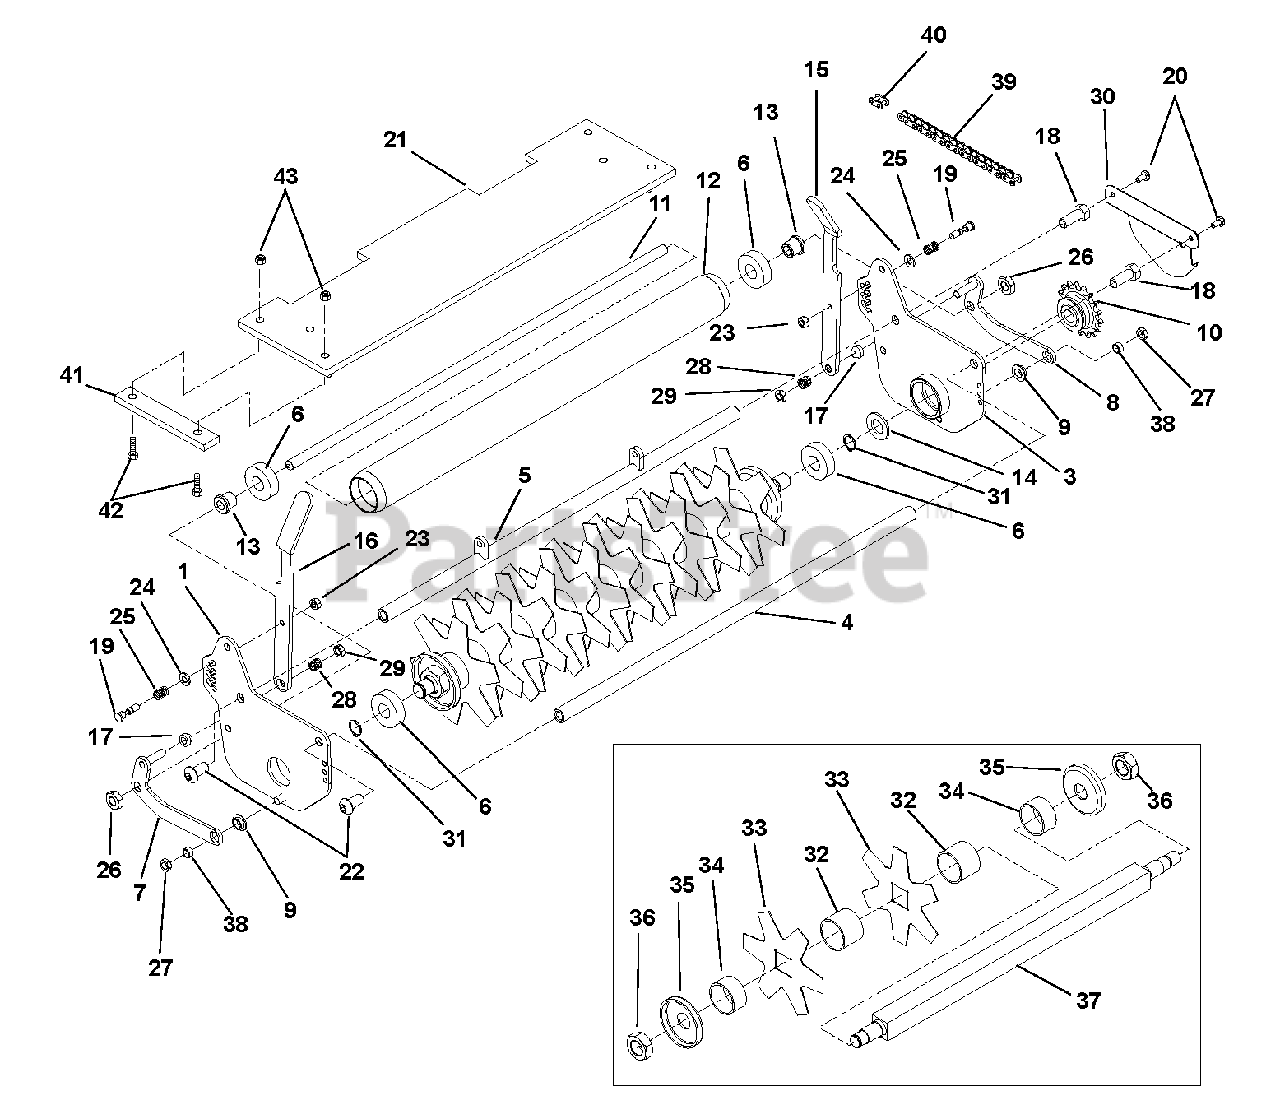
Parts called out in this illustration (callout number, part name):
1	Shaft Assembly, Verticutter (995030, 032)
2	End Plate, V-Cut Right Hand
3	End Plate, V-Cut Left Hand
4	Bar, Spacer 25-Inch (995030, 032)
5	Bar, Rear Spacer 25-Inch (995030, 032)
6	Bearing, 47 mm x 20 mm x 14 mm
7	Arm, Rear Roller Height Right Hand
8	Arm, Rear Roller Height Left Hand
9	Bushing, Sintered Steel, Oil Impregnated
10	Sprocket, 17 Tooth
11	Axle, Roller 25-Inch (995030, 032)
12	Tube, Roller 25-Inch (995030, 032)
13	Bushing
14	Shim
15	Handle, Quick Adjust Left Hand
16	Handle, Quick Adjust Right Hand
17	Bushing, 60 Degree
18	Cap Screw, Hex Head Special .50-13 x 1.25 (Hole)
19	Pin, Quick Adjust
20	Screw, Pan Head Slotted, Stainless Steel .25-28
21	Shield/Counterweight
22	Screw, Button Head .50-13 x 1 Stainless Steel
23	Nut, Hex .312-24
24	Washer, Quick Adjust
25	Spring, Quick Adjust
26	Nut, Nyloc Jam .50-20
27	Nut, Jam .375-24
28	Spring
29	Nut, Nyloc Jam .38-24
30	Chain Guard, Reel
31	Snap Ring, External .75
32	Spacer, Blade 1.50 x 2
33	Blade, Verti-Cut 6.5-Inch
34	Spacer, Blade 1.00 x 2
35	Washer, Shaft
36	Nut, Jam 1.0-14
37	Shaft, Verticutter (995030, 032)
38	Bushing
39	Chain, Reel Drive (56" # 423)
40	Master Link
41	Retainer, Verticutter Top Shield
42	Cap Screw, Hex Head .25-20 x 1.75
43	Nut, Hex Nyloc 025-2
